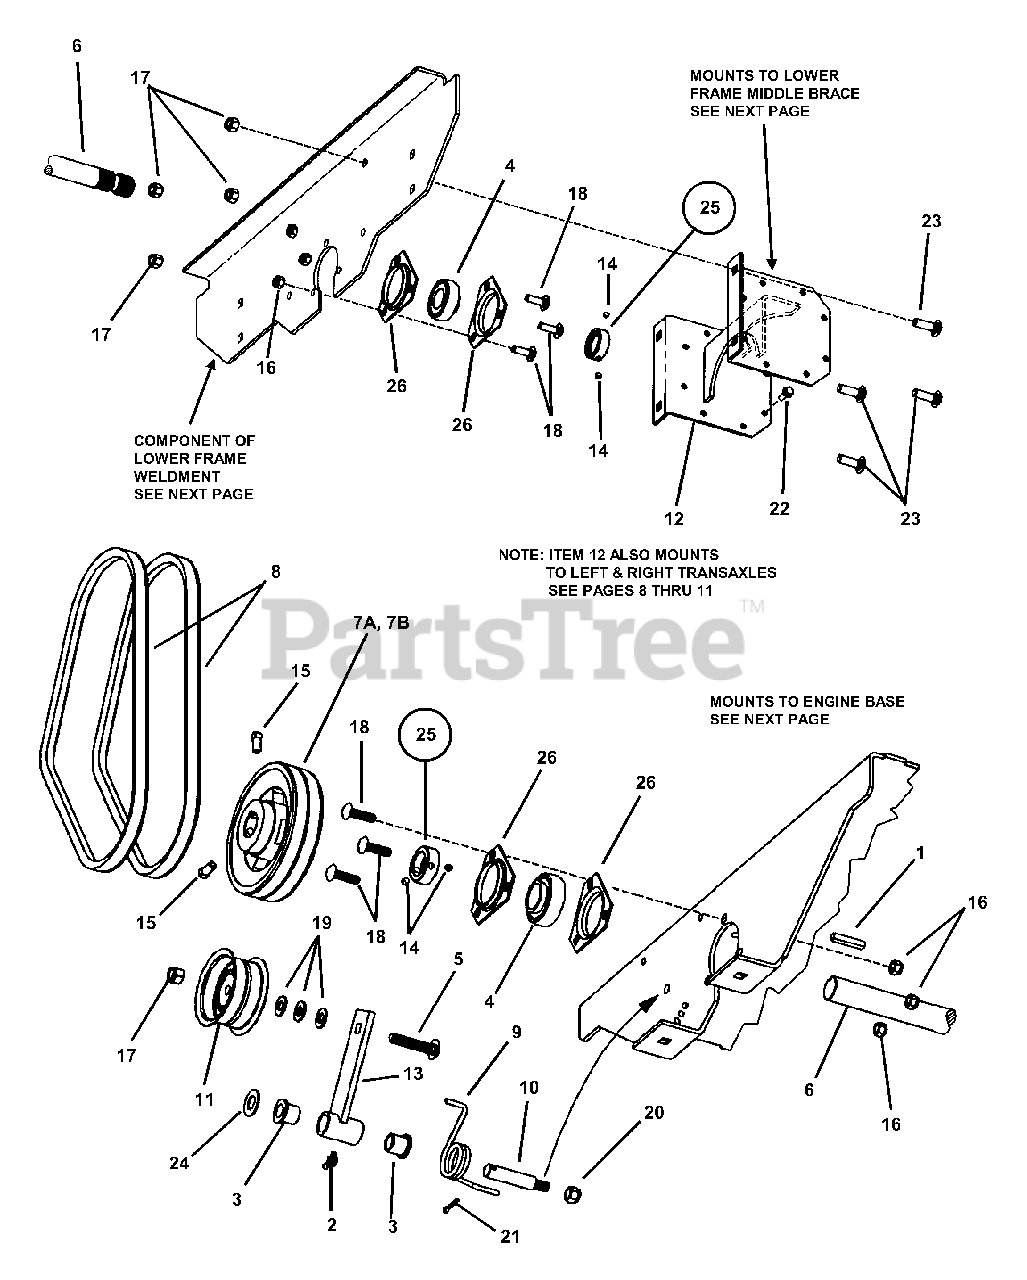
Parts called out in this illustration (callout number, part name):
1	KEY, 1/4 x 2" Square
2	FITTING, Lube
3	BUSHING
4	BEARING, 1" I.D.
5	BOLT, 3/8-16 x 2" Short Neck Carriage, Grade 2
6	DRIVE SHAFT, Deck (1" Diameter, 15 Spline)
7A	PULLEY, Double V (5.45 O.D., A Section)
7B	PULLEY, Double V (4.95 O.D., A Section) (Models ZMT2500KH, ZM2501KH, ZM2502KH)
8	BELT, Deck Drive (HA 36.5 Effective Length)
9	SPRING, Torsion
10	STUD, Idler (3/8-24 Thread)
11	FLAT IDLER, 2-3/4" O.D x 1-1/4" Wide
12	WELDMENT, Hydro Support
13	WELDMENT, Idler Arm
14	SET SCREW, 1/4-20 x 1/4" Socket Head, Cone Point
15	SET SCREW, 5/16-18 x 5/8" Socket Hd., Cup Pt.
16	NUT, 5/16-18 HEX NYLON LOCK
17	NUT, 3/8-16 HEX NYLON LOCK
18	BOLT, 5/16-18 x 1" Round Head Short Neck, Grade 5
19	WASHER, 3/8" Flat
20	NUT, 3/8-24 Hex Nyloc
21	COTTER PIN, 1/8 x 3/4"
22	SCREW, 1/4-20 x 5/8" Hex Flange Lock, Grade 5
23	BOLT, 3/8-16 x 1-1/4" Short Neck Carriage, Grade 5
24	WASHER, 9/16" Flat
25	ASSEMBLY, Lock Collar, 1" (with 1/4" Set Screw, item 14)
26	FLANGE, 1" Bearing
